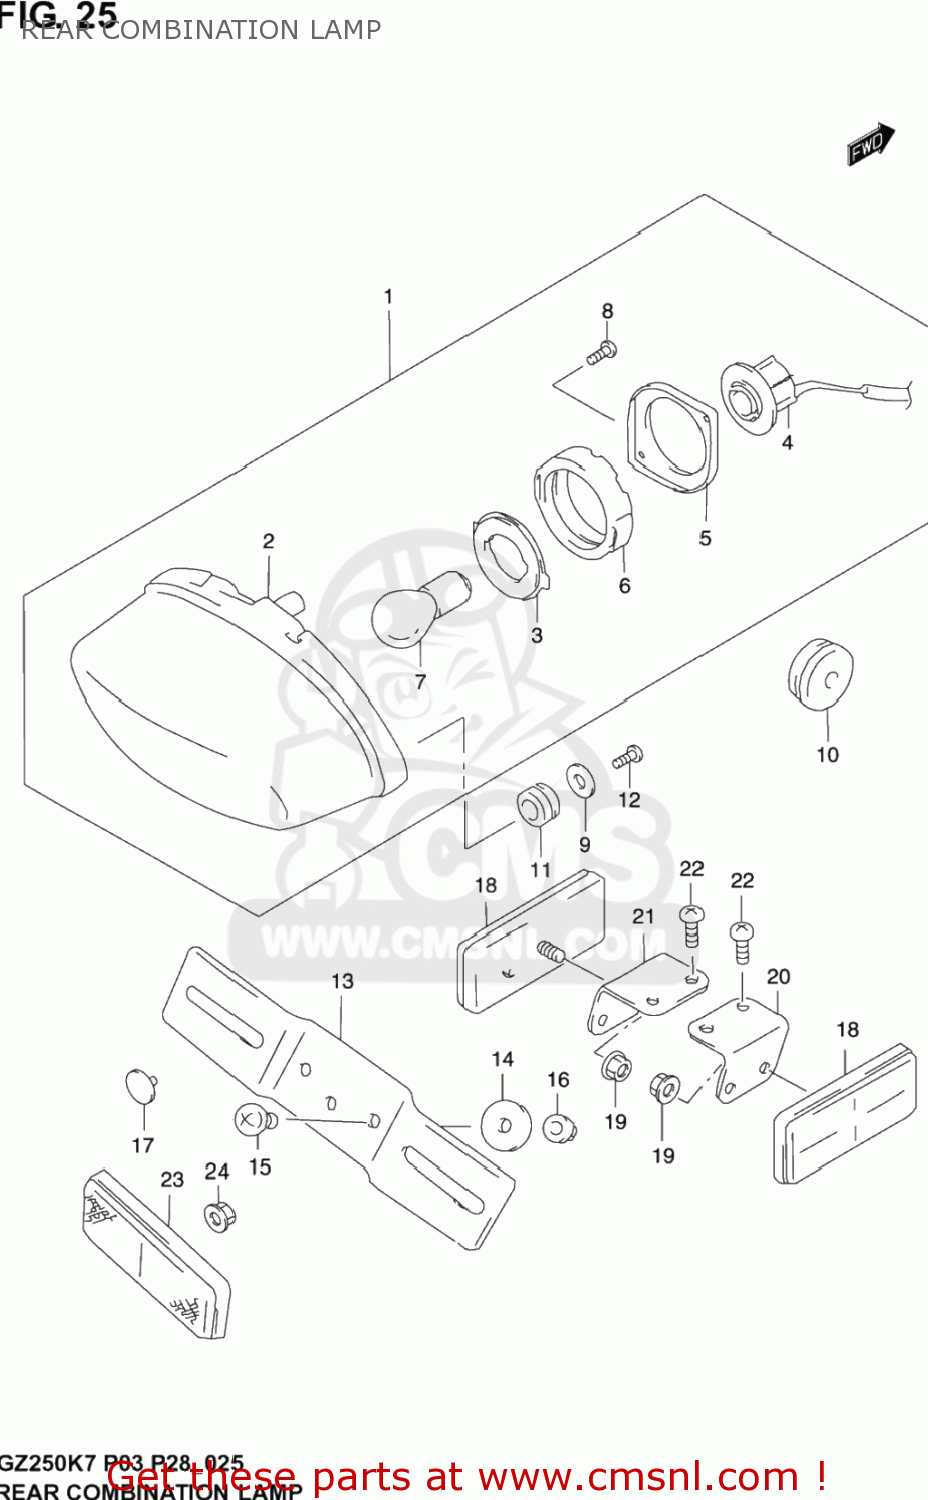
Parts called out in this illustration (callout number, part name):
1	LAMP ASSY,RR COMBINATION
2	LAMP UNIT
3	PLATE NO.1
4	SOCKET & CORD
5	PLATE NO.2
6	CUSHION
7	BULB(12V21/5W)
8	SCREW
9	WASHER(5.5X20X1.2)
10	GROMMET
11	CUSHION
12	SCREW
13	BRACKET,LICENSE PLATE
14	WASHER(6.5X20X1.6)
15	SCREW 6X12
16	NUT
17	CUSHION
18	REFLECTOR REAR
19	NUT
20	BRACKET,RR SIDE RR,L
21	BRACKET,RR SIDE RR,R
22	SCREW
23	REFLECTOR REAR
24	NUT
